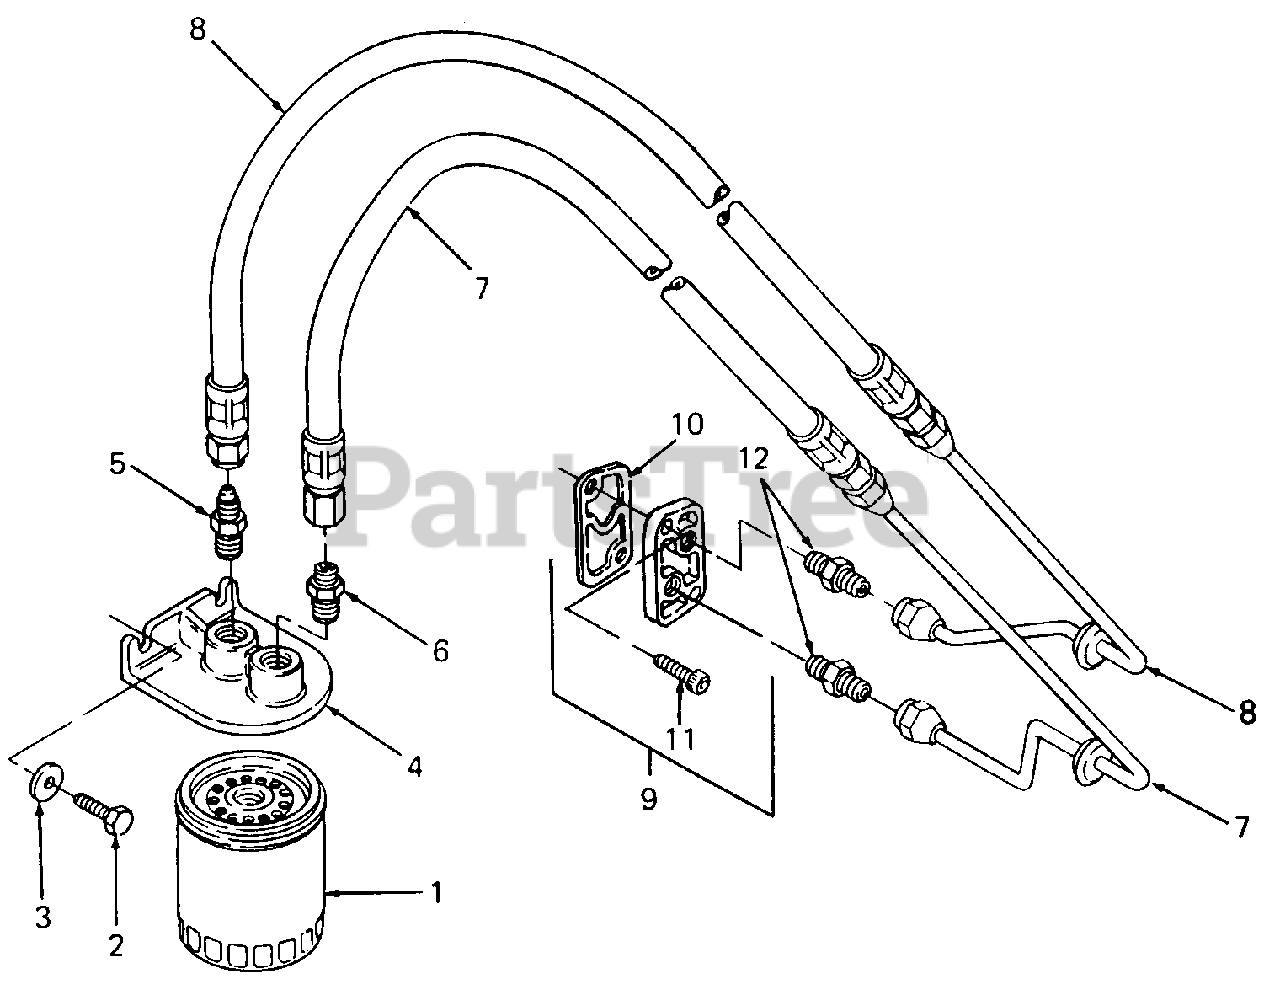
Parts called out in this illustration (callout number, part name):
1	Oil Filter
2	Screw, Hex Cap, 5/16-18 X 1.0 Lg GR5
3	Washer, Bell, .380 X .88 X .060 Thk
4	Adapter, Remote Oil Filter
5	Nipple, Hexagon
6	Connector, Reducing
7	Oil Line - 20.5 Long
8	Oil Line - 22.5 Long
9	Kit, Oil Filter Cover
10	Gasket, Oil Filter Cover
11	Screw, Hex Socket Hd Cap, 5/16-18 X 1.25 Lg
12	Connector, Reducing
